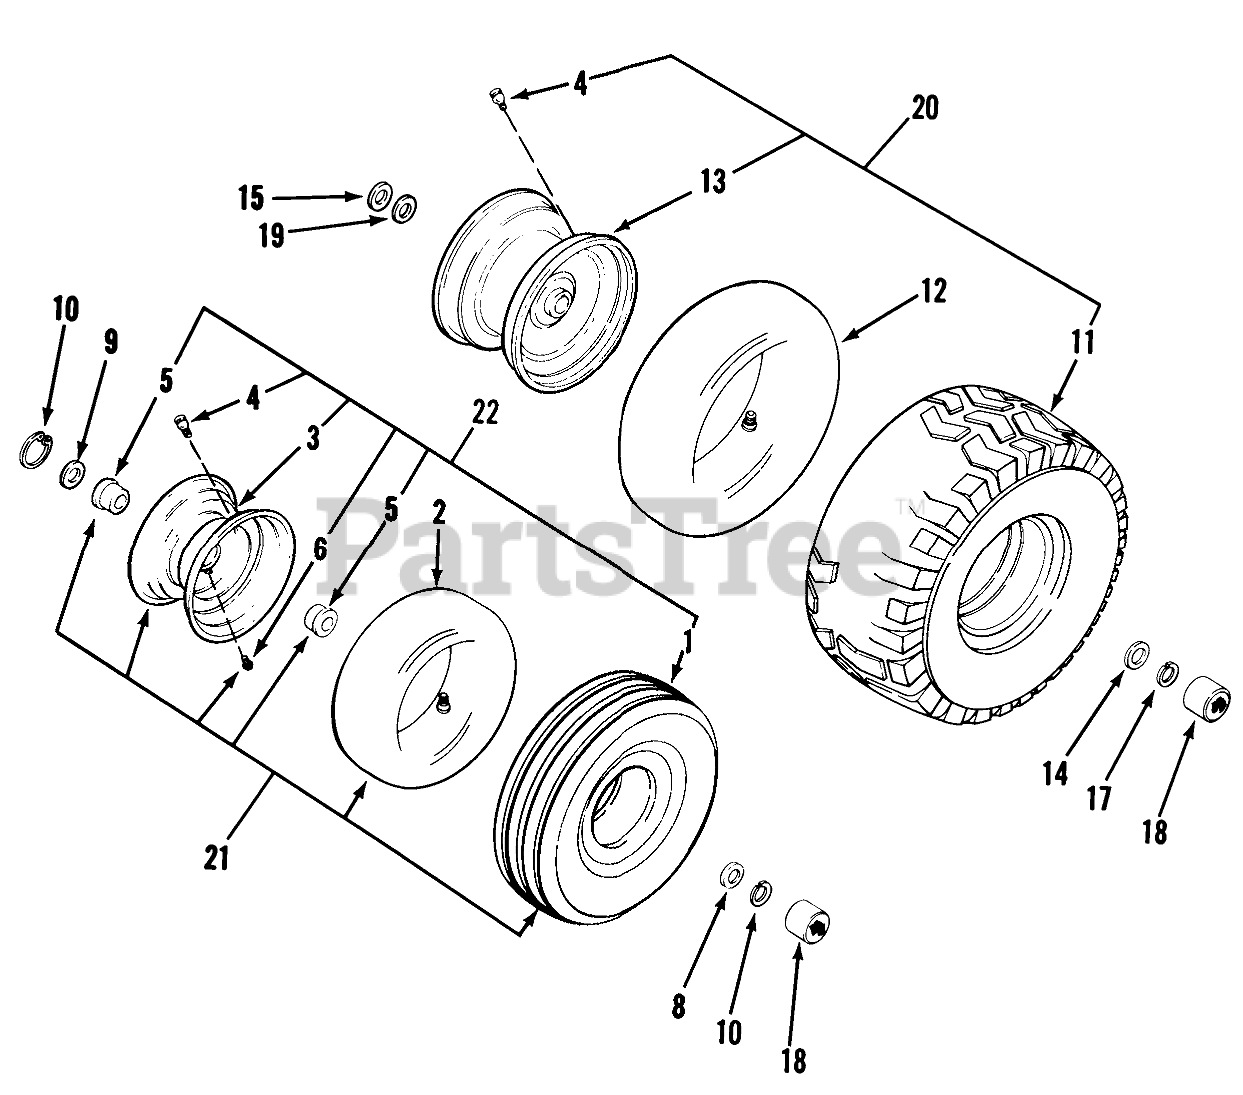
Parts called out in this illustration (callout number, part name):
1	Tire-Front 4-10 X 3.50-4
3	Wheel-Front (Includes Item Numbers 5, 6)
4	VALVE
5	BUSHING-FLANGED
8	WASHER-FLAT
9	WASHER-SHIM
9	WASHER
11	TIRE
13	Wheel-Rear (Includes Item Number 4)
14	WASHER-FLAT
15	WASHER
19	WASHER-SHIM
20	Rear Wheel and Tire Assy
21	Front Wheel and Tire Assy
